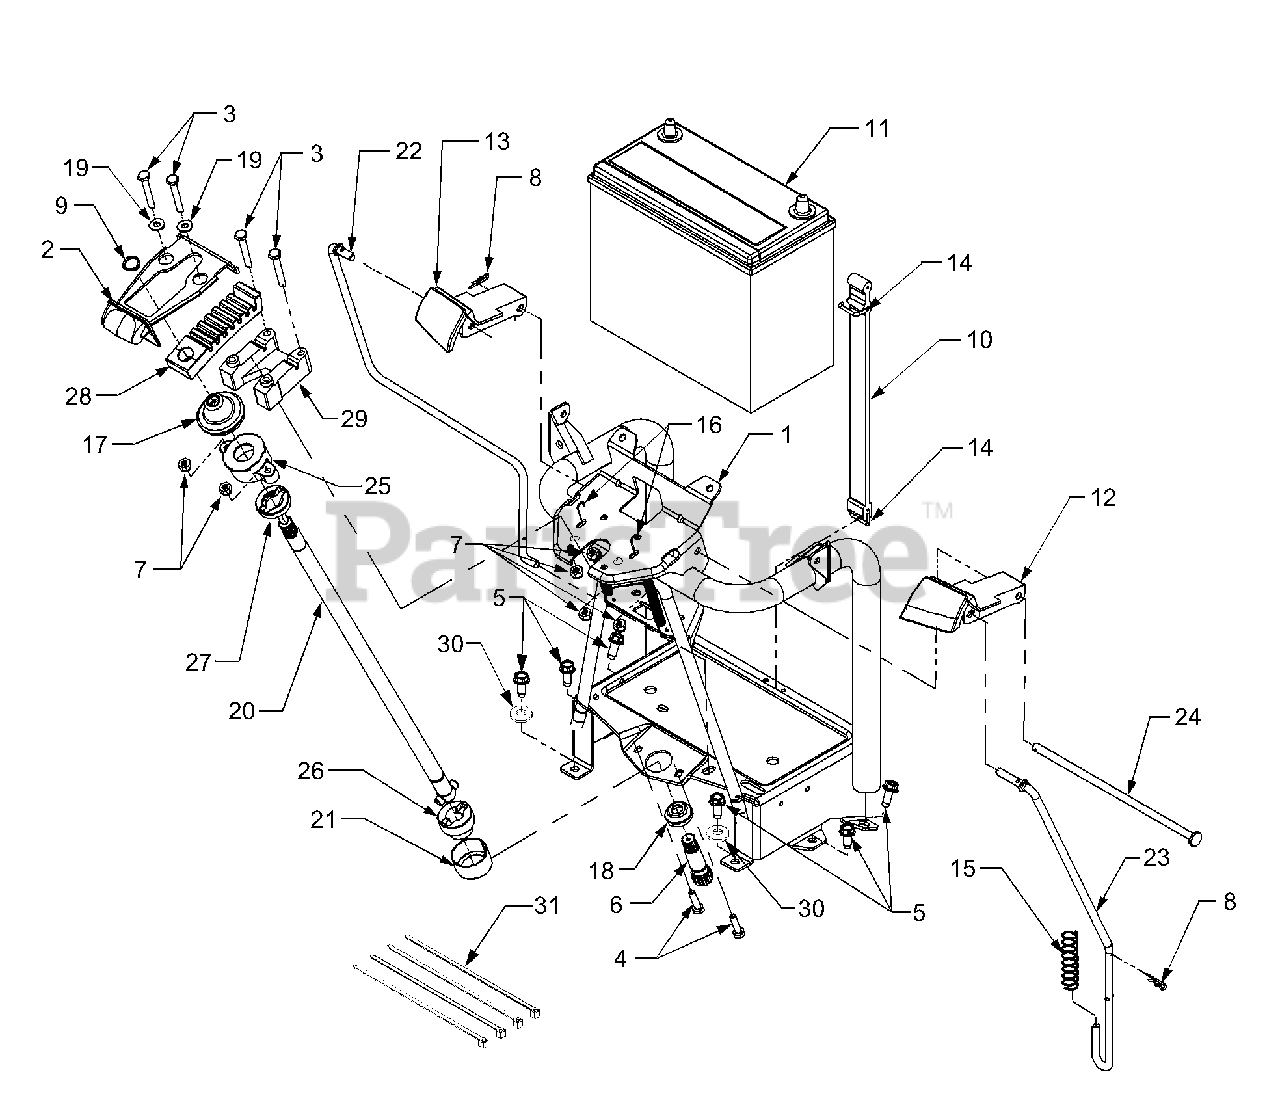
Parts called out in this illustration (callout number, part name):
1	Pedestal Assembly
2	Handle, Tilt
3	Screw, Hex Cap 1/4-20 x 1.75 GR5
4	Screw, Hex Cap 1/4-20 x 1.0 GR5
5	Screw, Hex Wash. Hd. Tapp 5/16-18 x .75
6	Shaft, Lower Steering
7	Nut, Hex Insert Lock, 1/4-20
8	Pin, Internal Cotter
9	Ring, Retaining, .56 Dia Shaft
10	Strap, Battery
11	Battery
12	Lever, Park Brake
13	Lever, Cruise
14	Hook, Wire Rectangular
15	Spring, Compression, .676 x 2.57
16	Spring, Extension
17	Boot, Tilt Wheel Coupling
18	Boot, Shaft Cover
19	Washer, Flat, .271 x .63 x .065
20	Shaft, Upper Steering
21	Bearing, Sleeve, 1.44 x 1.5 x .812
22	Rod, Cruise Control
23	Rod, Parking Brake
24	Rod, Cruise/Brake Pivot
25	Housing, Tilt Wheel Coupling
26	Coupling Half, Bottom
27	Coupling Half, Top
28	Index, Tilt Steering
29	Block, Tilt Steering
30	Washer, Flat, .344 x .688 x .065
31	Cable Tie, Harness
